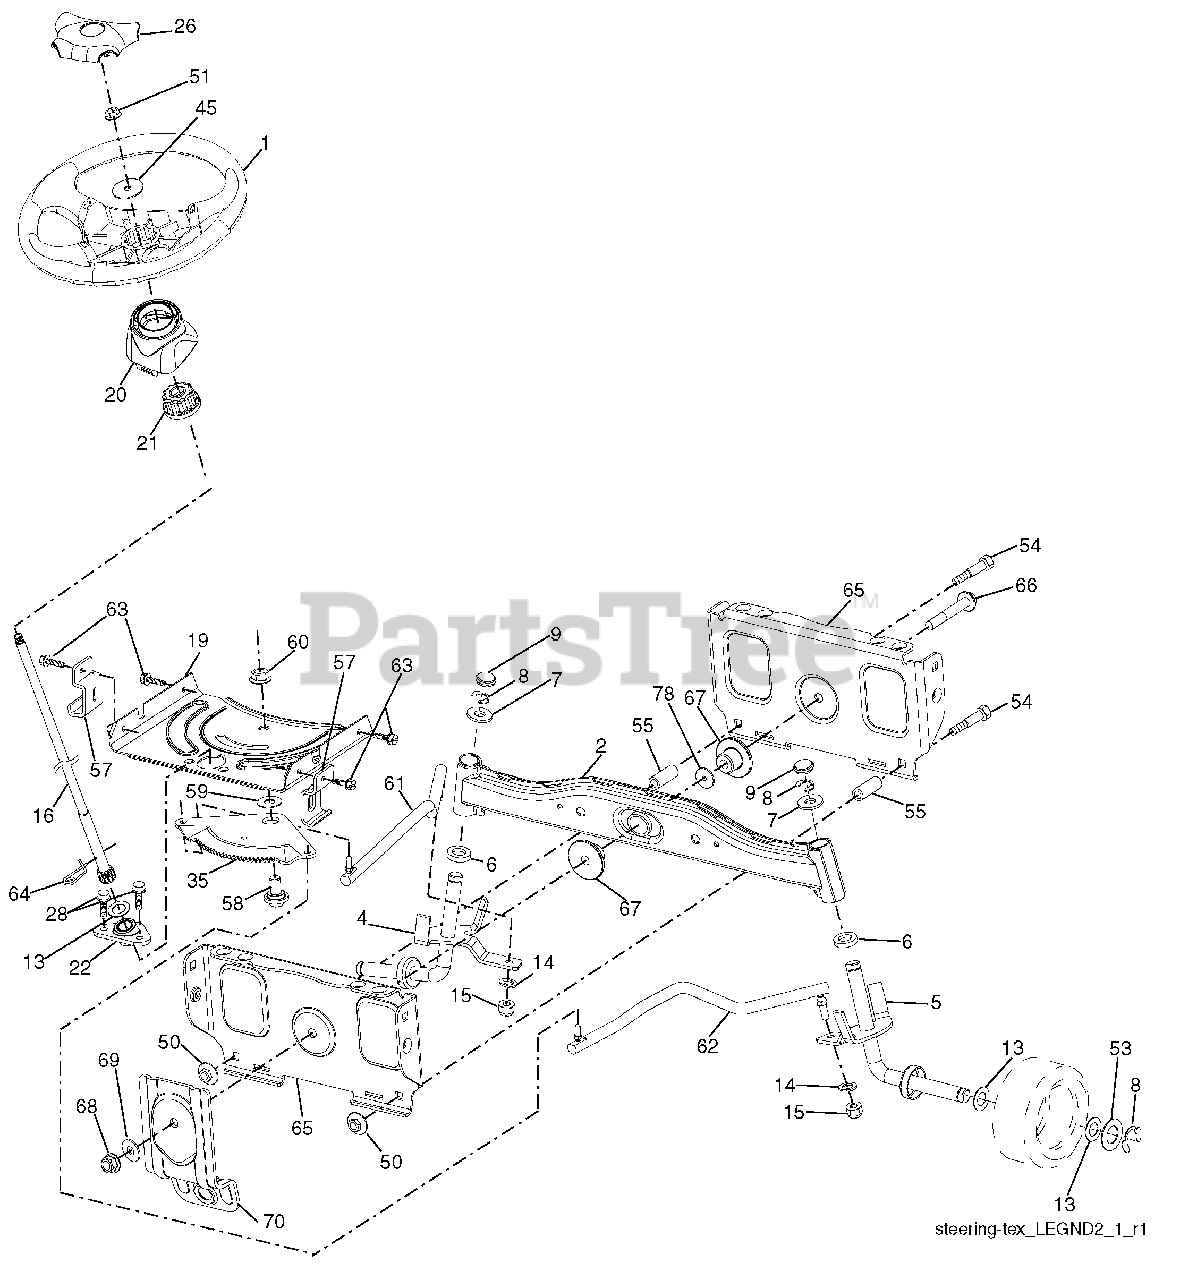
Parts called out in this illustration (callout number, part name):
1	Wheel, Steering
2	Axle Asm., Front
4	Spindle Asm., LH
5	Spindle Asm., RH
6	Bearing, Race Thrust Harden
7	Washer 25/32 x 1-5/8 x 16 Ga.
8	Ring, Clip #T5304-75
9	Cap, Spindle
13	Washer 25/32 x 1-1/4 x 16 Ga.
14	Washer, Lock Hvy Hlcl Spr 3/8
15	Nut, Crown Lock 3/8-24 unf
16	Shaft Steering
19	Plate Steering
20	Boot, Steering
21	Adapter, Wheel Steering
22	Bushing, Strg. Blk
26	Insert, Wheel Steering
28	Screw 3/8-16 x 3/4
35	Gear, Sector Plate
45	Washer 9/16 ID x 2-3/8 x 12 Ga.
50	Nut Lock 3/8-16 unc
51	Nut Hex Jam Toplock 1/2-20 unf
53	Washer Hardened .793 x 1.637 x .060
54	Bolt Hex 3/8-16 unc x 2-1/4
55	Spacer Brace Axle
57	Bracket Upstop
58	Bolt Shoulder Sector Pivot CFM
59	Washer Thrust Sector Steering
60	Nut Flange Lock 5/8-11
61	Draglink, LH
62	Draglink, RH
63	Screw 5/16-18 x 3/4
64	Retainer Clip Spring Steering
65	Brace Axle Front
66	Bolt Hex Fghd 7/16-14 x 3 Serr
67	Bushing PM Front Axle
68	Nut Lock Flange 7/16-14 Gr. 5
69	Washer 1.5 x .505 x .118
70	Bracket Deck Susp. Front
78	Washer Thrust .515 x .750 x .033
